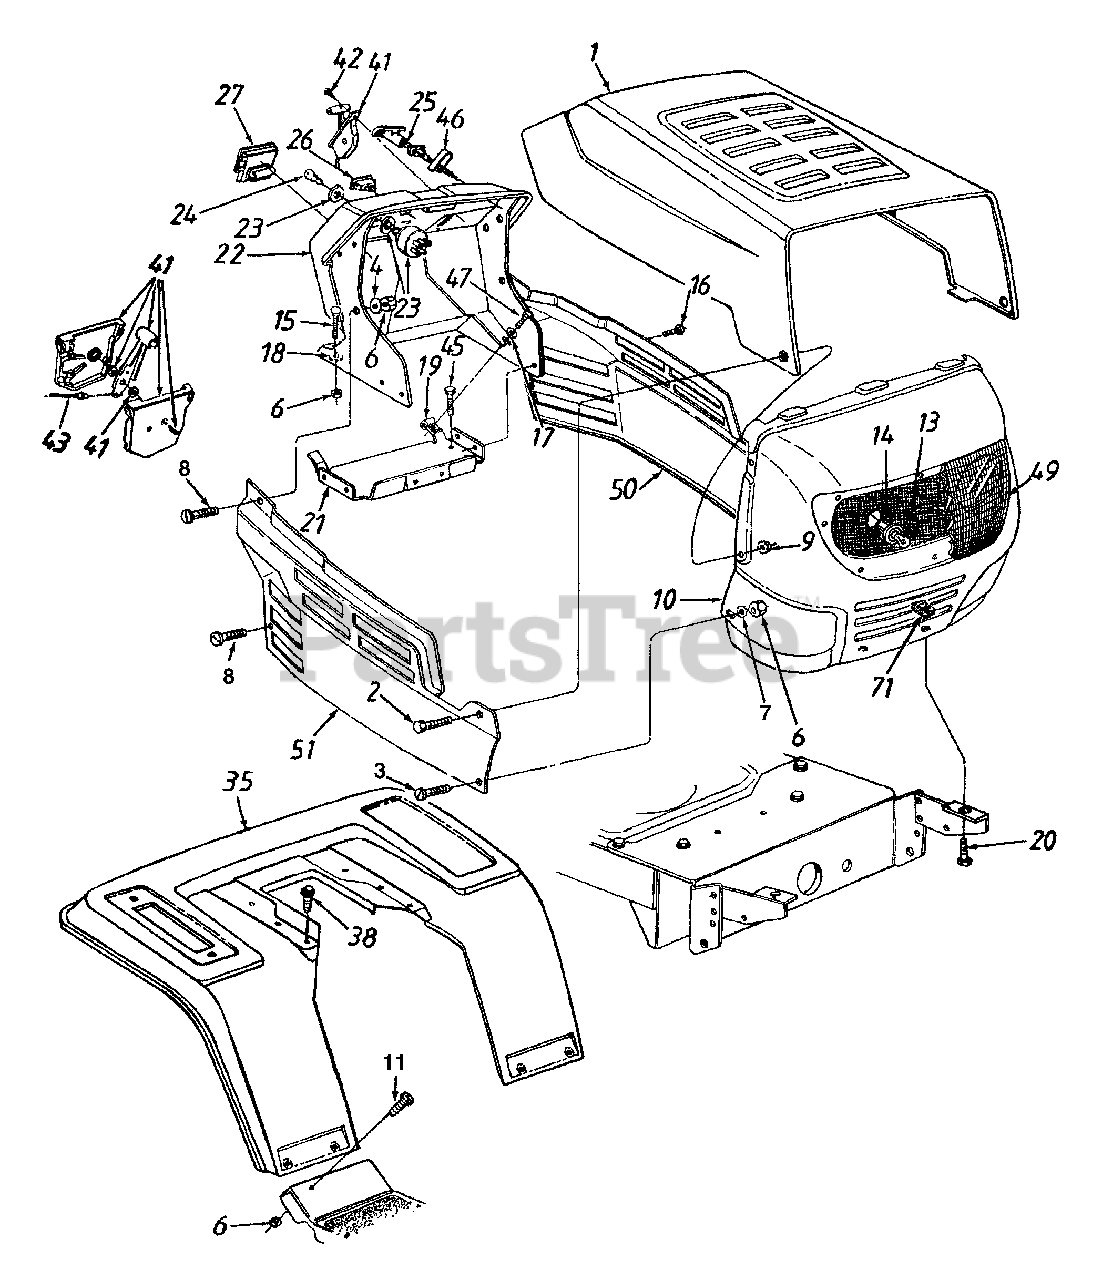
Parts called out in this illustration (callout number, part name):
1	Hood
2	Shld. Bolt .375" Dia. x .125" Lg.
3	Scr. 1/4-20 x .75
4	Wash. .283 x .030
6	Hex Sems Nut 1/4-20 Thd.
7	Bell.Washer .265 x .75" Lg.
8	Hex Wash. Hd. TT-Tap Scr. 1/4-20 x .75" Lg.
9	Flange L-Nut 1/4-20 Thd.
11	Hex Hd. Cap Scr. 1/4-20 x .62" Lg.
13	Lamp
14	Socket
15	Carriage Bolt 1/4-20 x .75" Lg.
16	Hex Wash. Hd. TT-Tap Scr.1/4-20 x .5" Lg.
17	Fl-Wash. .281" I.D. x .73" O.D.
18	Bolt Retainer 1/4" I.D.
19	Speed Nut 1/4-20
20	Hex Bolt 5/16-18 x .75" Lg.
23	Ignition Switch
24	Ignition Key
25	Choke Control
26	Light Switch
27	Ammeter
38	Hex Wash. Hd. AB-Tap Scr. 5/16 x .75" Lg.
41	Throttle Box Ass'y.
42	Truss Mach. AB-Tap Scr. #10 x .5" Lg.
43	Throttle Control Wire
45	Hex Wash. Hd. B-Tap Scr. 5/16-18 x .5" Lg.
46	Choke Retainer
47	Hex TT-Tap Scr. 1/4-20 x .75" Lg.
49	Lens
71	U-Nut 5/16-18 Thd.
